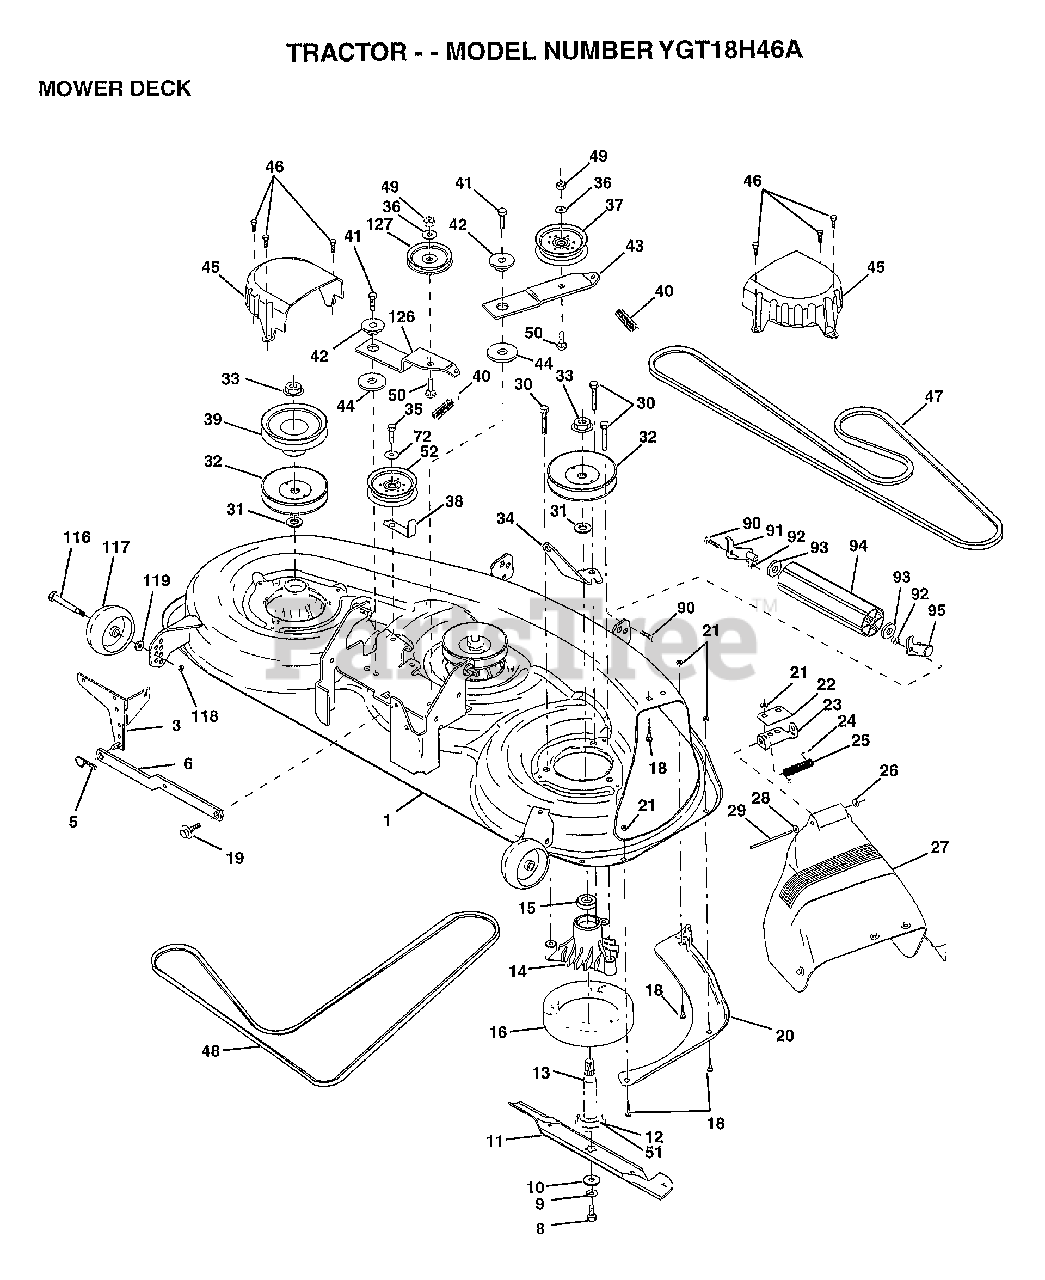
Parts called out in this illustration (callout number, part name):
1	HOUSING MOWER
3	BRKT.ASM.SW.44/50
8	BLADE BOLT
10	WASHER.HARD.BLADE
12	BEARING.BALL
13	SHAFT.ASM.W/BRNG
14	HOUSING.MAND.44.V
15	BEARING
16	STRIPPER RND MWR
18	BOLT
19	BOLT SHD 5/16-18
20	BAFFFLE.VORTEX.46
22	STIFFENER BRKT
23	DEFLECTOR BRKT
24	CAP-SLEEVE LT
25	SPRING TORSION
26	NUT PUSH M
28	WASHER
29	HINGE ROD
31	WASHER
32	PULLEY.MAND.36/46
34	ANCHOR.SPRING.46
35	SCREW LT
36	WASHER
37	FLAT IDLER PULLEY
38	"KEEPER BELT,IDLER"
39	PULLEY.DRV.DCK.46
40	"SPRING.SEC.44""VEN"
41	SCREW
42	SPACER RETAINER
43	ARM.IDLER.DECK.46
44	HARDENED WASHER
45	COVER.MANDREL.46
46	SCREW.1/4-20X5/8
47	BELT-V.SEC.46.KEL
48	BELT.MWR.PRM.85.4
50	BOLT.3/8-16X1.50
51	WASHER.FELT.
52	PULLEY.IDLER.
53	WASHER
54	BOLT
72	WASHER HYT
90	BOLT
92	NUT
93	WASHER
101	COVER.MULCHING.
102	SCREW
103	LOCKWASHER
104	WASHER #10
106	WELDNUT
116	BOLT.SHOULDER
117	WHEEL GAGE DONUT
118	LOCKNUT
119	WASHER
126	ARM.IDLER.PRIM.46
127	PULLEY.IDLER.4.25
